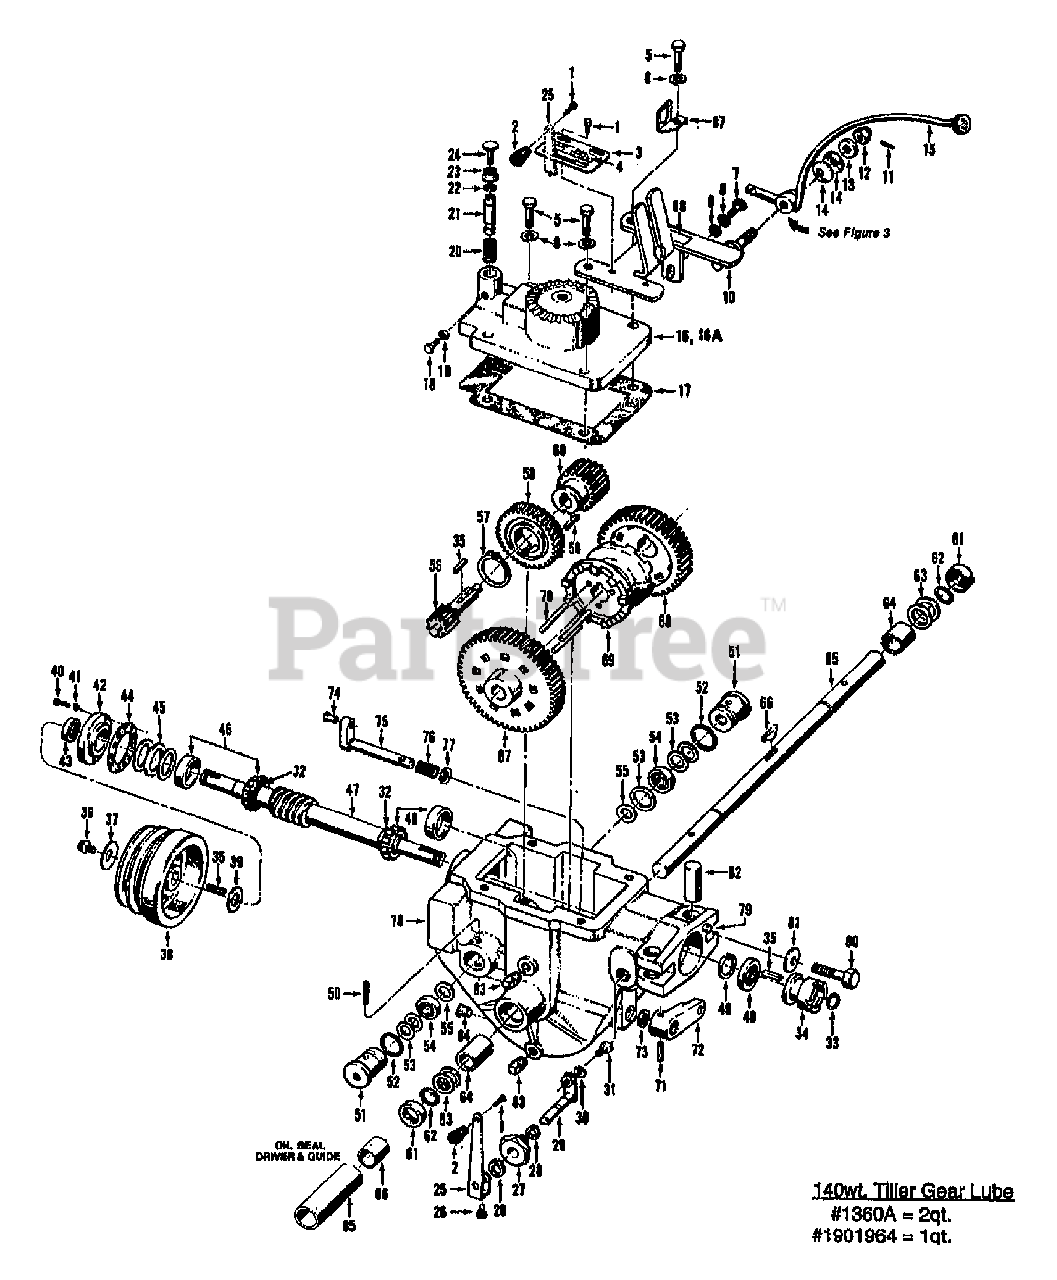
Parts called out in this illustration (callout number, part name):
1	SCR 10-32
2	KNOB-TAPERED
3	PLATE-TINE ENGAGE W/DECAL INCLUDES #2599 OPER- ATING DECAL (REF. #4)
4	DECAL-TINE ENGAGE
5	BOLT-HH 3/8-16X1.5 FTH ZP
6	WASHER-LK .375
7	SCR-HFLK 5/16-18X.75 ZP
8	WASHER-LK .312 ZP
9	WASHER-FLAT 5/16 SAE
10	BRKT-H HOOD 2149
11	PIN-SPRING .125 X 1
12	NUT-HEX 1/2-20
13	WASHER-# SHOULDER ZP
14	WASHER-# 1.97X1X.118
15	LEVER-WHEEL SPEED SHIFT
16	COVER-TRANS RED 2523
16A	ASSM-TRANS COVER OPC
17	GASKET-TRANS COVER
18	SCR-HH 5/16-18X1.0 G5 ZP
19	NUT-HEX 5/16-18 ZP
20	SPRING-REV PLUNGER ZP
21	ASSM-NEUTRAL PLUNGER
22	RING-KLIP EXT .594 ID ZP
23	NUT-HFLK 3/8-16 ZP
24	SCR 3/8-16X1.5 UNC-2AG
25	LEVER-ECCENTRIC RED
26	SCR-HH 1/4-20X.5 GR5 YEL
27	BUSHING-.87X.5X.62 ECC
28	RING-RETAINING 5100-50
29	ECCENTRIC-SHAFT,TINES/PTO CLUTCH LEVER
30	WASHER-LK .25 HI-COLLAR
31	SCR-HXSKT 1/4-20X.38 G8
32	WASHER-#1.25X.75X.06
33	RING-RETAIN EXT .707 ID
34	KIT-CLUTCH DOGS TILLER
35	KEY-.188 SQX1.0
36	SCR-HH 5/16-24X.75 G5 ZP
37	WASHER-.827X.331X.098
38	PULLEY-TRANS MACH
39	WASHER-SHLDR HARDENED
40	SCR-HH 1/4-20X.75 G5 ZP
41	WASHER-LK .25 ZP
42	COVER-FRONT
43	SEAL-PINION SHAFT PT/85030/00
44	GASKET-BRG COVER
45	SHIM-1.75X1.5X.01
45	SHIM-1.75X1.5X.03
45	SHIM-1.75X1.5X.005
45	SHIM-1.75X1.5X.062
46	KIT-BRG CONE&RACE-DRIVESHAFT
47	KIT-TRANS DRSHAFT HORSE
48	SEAL-OIL DRIVESHAFT
49	RING-RETAINING 5000-181
50	PIN-SPIROL .25 X 2.0
51	PLUG-PINION BRG W/RING
52	RING-O 1 ID
53	SHIM-1.234X1.015X.033
53	SHIM-1.234X1.015X.062
53	SHIM-1.234X1.015X.01
54	BRG-BALL (7 BALLS)
55	WASHER-# 1X.484X.06
56	GEAR-SPLINE 10 TEETH MACH
57	RING-RETAINING 5100-150
58	GEAR-WORM 36 TEETH MACH
60	GEAR-SPUR 20 TEETH MACH
61	SEAL-OIL WHEELSHAFT
62	RING-HEAVY EXT .906 ID
63	SHIM-1.375X1.015X.062
63	SHIM-1.375X1.015X.03
63	SHIM-1.375X1.015X.015
63	SHIM-1.375X1.015X.01
63	SHIM-1.375X1.015X.005
64	BUSHING-1.25X1.005X1.5
65	KIT-WHEELSHAFT
66	KEY-HI PRO .25X1.812
67	GEAR-SPUR 56 TEETH MACH
68	GEAR-SPUR 46 TEETH MACH
69	CLUTCH-MACH
70	PIN-CLUTCH .25 2.65
71	PIN-SPIROL .188 X 1.25
72	LEVER-ECC. #1029
73	SEAL-OIL ECCENTRIC
74	PIN-.375 X .72
75	SHAFT-ECCENTRIC HORSE TLR
76	SPRING .845 X 1.25
77	WASHER # .875 X .65 X .06
78	CASE-TRANS W/PIN
79	PIN-DRIVE .375X.75 ZP
80	SCR-HH 1/2-13X2.0 G5 ZP
81	WASHER-DISC SPRING
82	POST (TC)
83	PLUG-PIPE 1/4 NPT
84	PLUG-CAP (RED)
85	DRIVER-PLASTIC
86	SEAL-DRIVER PILOT
87	CLIP-CONNECTOR
88	DECAL-FWD INTERLOCK WIRE
